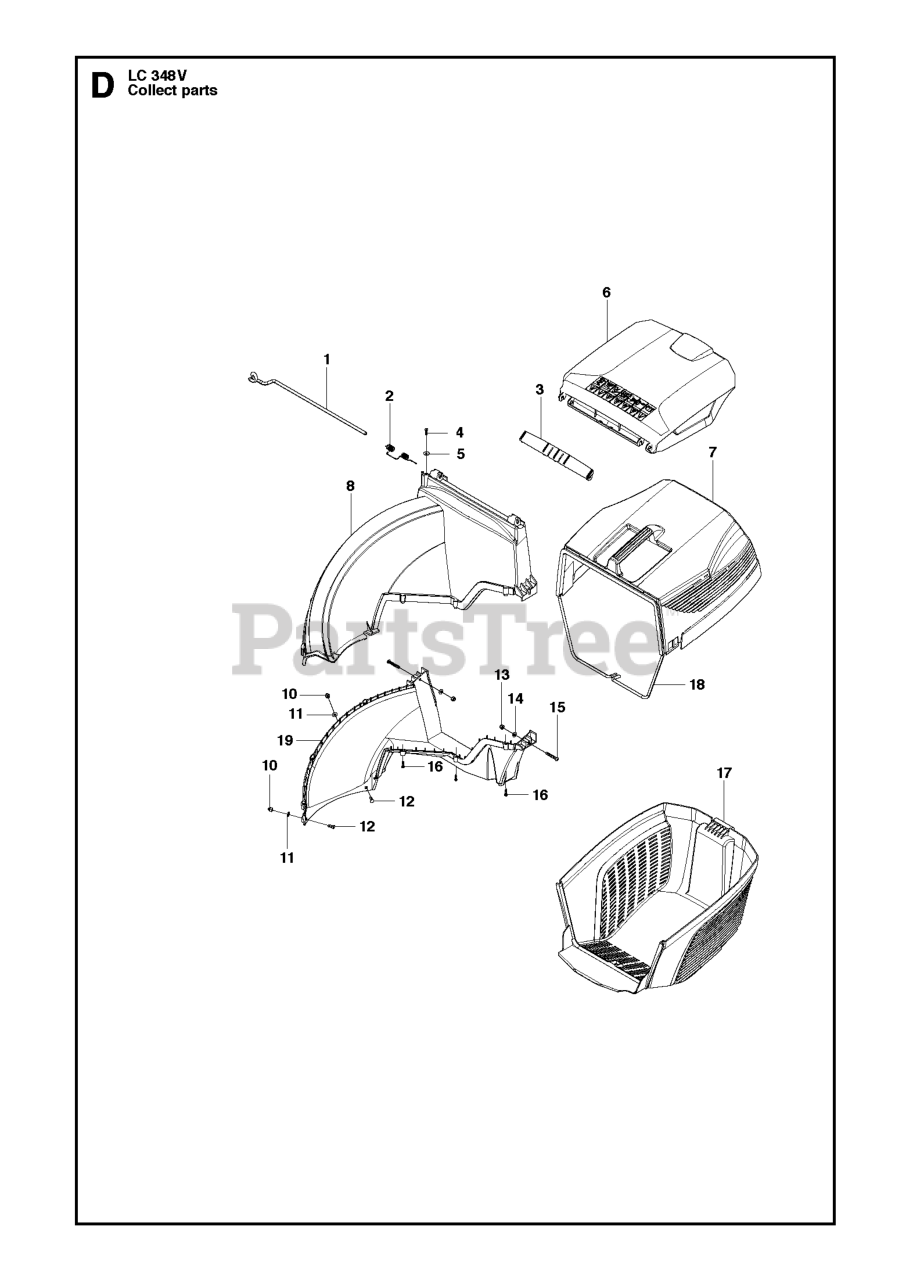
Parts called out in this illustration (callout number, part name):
1	AXLE HATCH REAR DISCHARGE
2	SPRING SAFETY FLAP A009
4	CHUTE LOWER A009
6	HATCH REAR DISCHARGE
7	GRASSBAG UPPER
8	CHUTE UPPER A009
16	SCREW ITXPANT T50X16 ZN/FE (A
17	GRASSBAG LOWER
19	CHUTE LOWER A009
